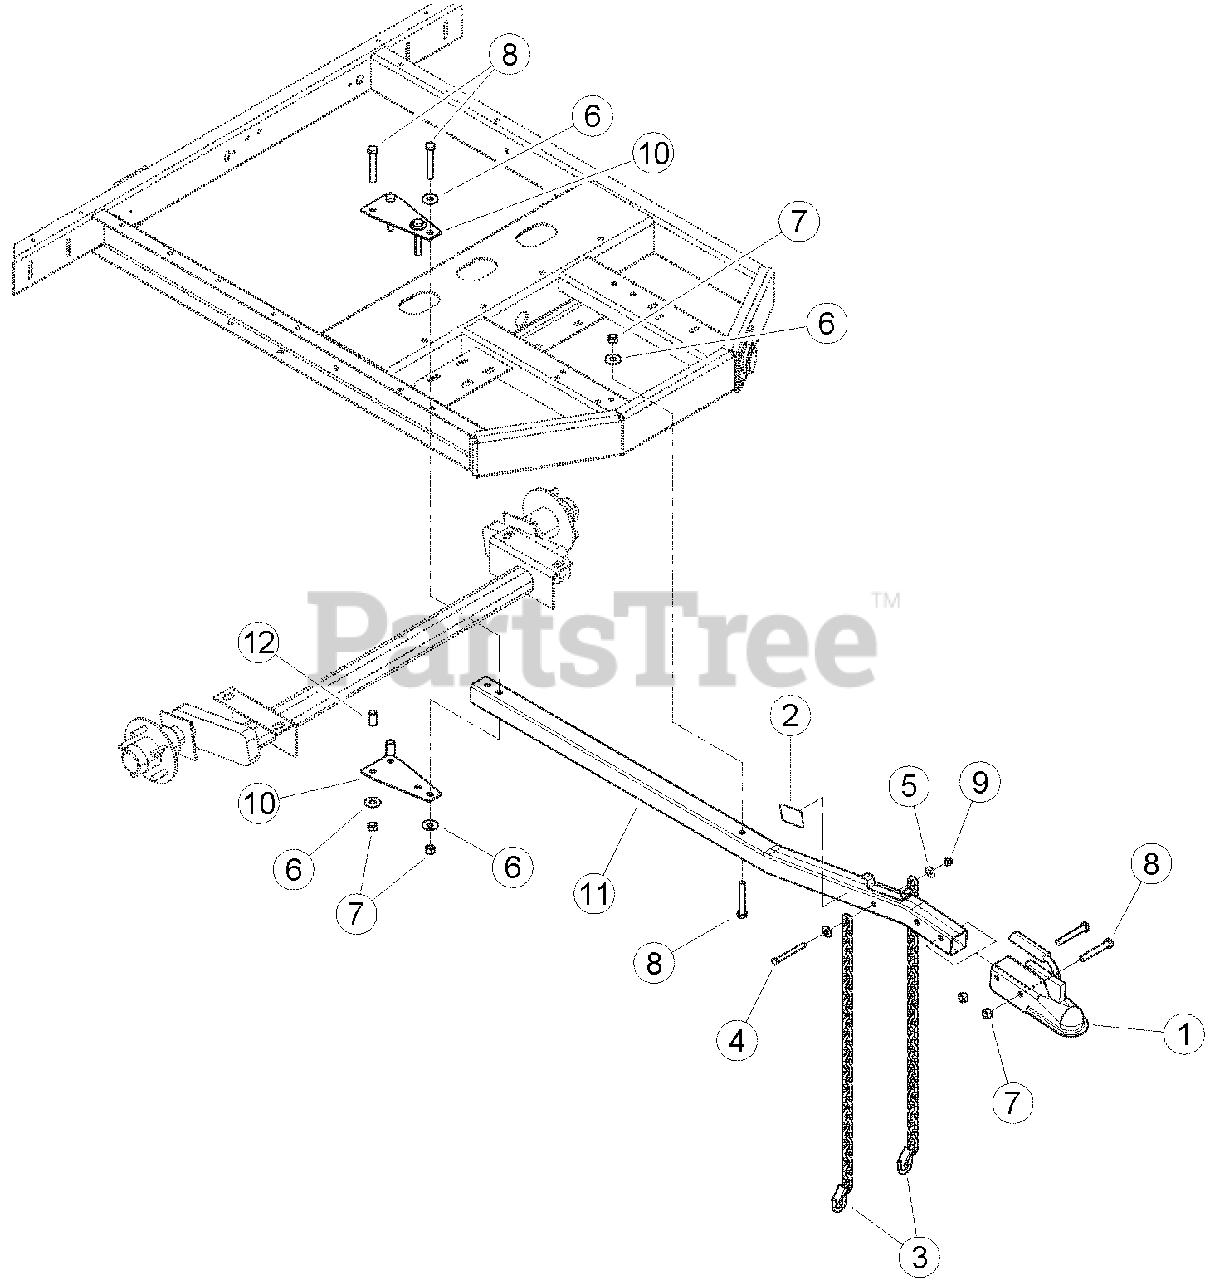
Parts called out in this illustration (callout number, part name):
1	COUPLER, 50 MM BALL
2	REFLECTOR, WIDE ANGLE AMBER
3	CHAIN, SAFETY, 5000 LB W/LATCH
4	BOLT, 3/8 X 3-1/2 HEX HD GR5 ZP
5	WASHER, 3/8 FLAT ZP
6	WASHER, 1/2 FLAT ZP
7	NUT, 1/2 CENTERLOCK GRB ZP
8	BOLT, 1/2 X 3-1/4 HEX HD GR5 ZP
9	NUT, 3/8 NYLOCK
10	PLATE, AXLE SAFETY
11	WELDMENT, HITCH POLE S-MODEL 2 IN.
12	SPACER, 0.75 X 1.180 BLACK
